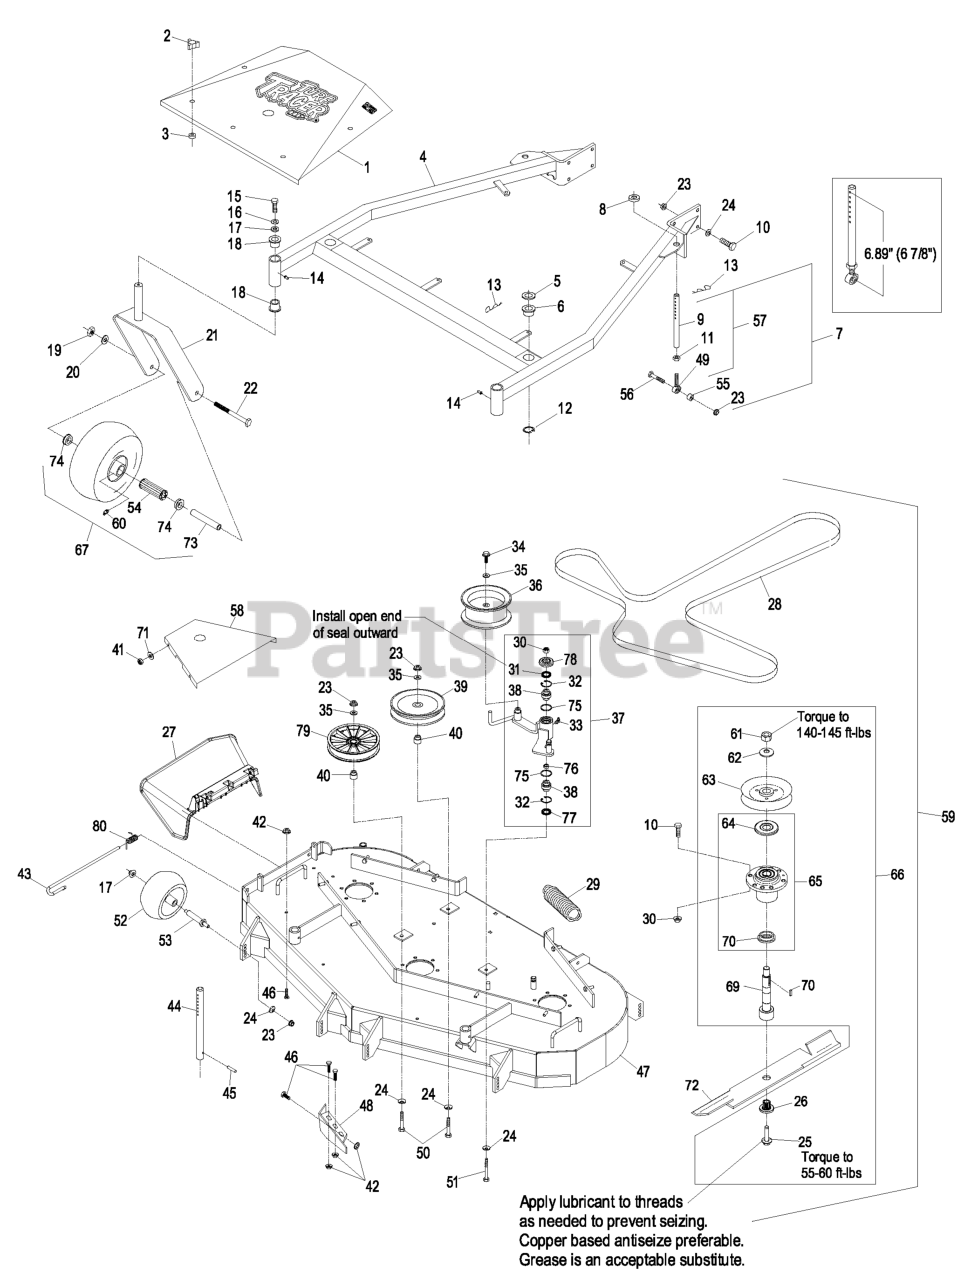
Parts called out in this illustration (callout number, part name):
1	ASM,SHIELD W/DECALS 52 TT
2	KNOB-3 PRONG
4	SUPPORT,DECK W/BUSHINGS
5	SPACER-DECK SUPPORT
6	BUSHING-DECK
7	KIT,SUPPORT LINK W/PIN
9	LINK,SUPPORT
10	SCREW-HH
11	NUT-HJ
12	RING-RETAINING
13	PIN,HAIR COTTER
14	FITTING-GREASE
15	SCREW-HH
16	WASHER-LOCK
18	BEARING-FLANGED
19	NUT-HH
20	WASHER-LOCK
22	SCREW-HH
23	NUT-HHF, WHIZ
24	WASHER-BELLEVILLE
25	SCREW,SEMS 1/2-20 X 2.19
26	BUSHING,SPLINED
27	CHUTE DEFLECTOR XRK M056
28	BELT,DECK DRIVE
30	NUT-LOCK, NI
31	SEAL-LIP, SINGLE
32	RING-SNAP
33	FITTING-GREASE, 90 DEG
34	SCREW-HHF
35	WASHER-FLAT
37	KIT, DECK IDLER TTHP48&52
38	BEARING-SPHERICAL
39	PULLEY-IDLER
40	BUSHING-IDLER
41	NUT-LOCK, NI
43	PIN-CHUTE
44	ROD,DECK SUPPORT
46	SCREW-HH
47	ASM,DECK W/DECALS TTHP52
48	WLD,BAFFLE DISCHARGE
49	BALLJOINT
50	SCREW-HH
51	SCREW-HH
52	ROLLER-SCALP, ANTI
54	BEARING
56	SCREW-HH
58	SHIELD,SIDE BELT 52
59	Asm, Deck Complete
60	FITTING-GREASE
63	SHEAVE,W/HUB 5.72
64	GUARD-BEARING, TOP
65	KIT, CUTTER HOUSING
66	ASM, CUTTER HSG
67	KIT, SP CASTER WHEEL REPL
68	SPACER-GUARD, BOTTOM
69	KIT, SPLINED SPINDLE 103-
70	KEY-RECTANGLE
71	WASHER-FLAT
74	BUSHING
77	SEAL-LIP, DOUBLE
78	GUARD-TOP
79	PULLEY,IDLER 5"
80	SPRING, TORSION
